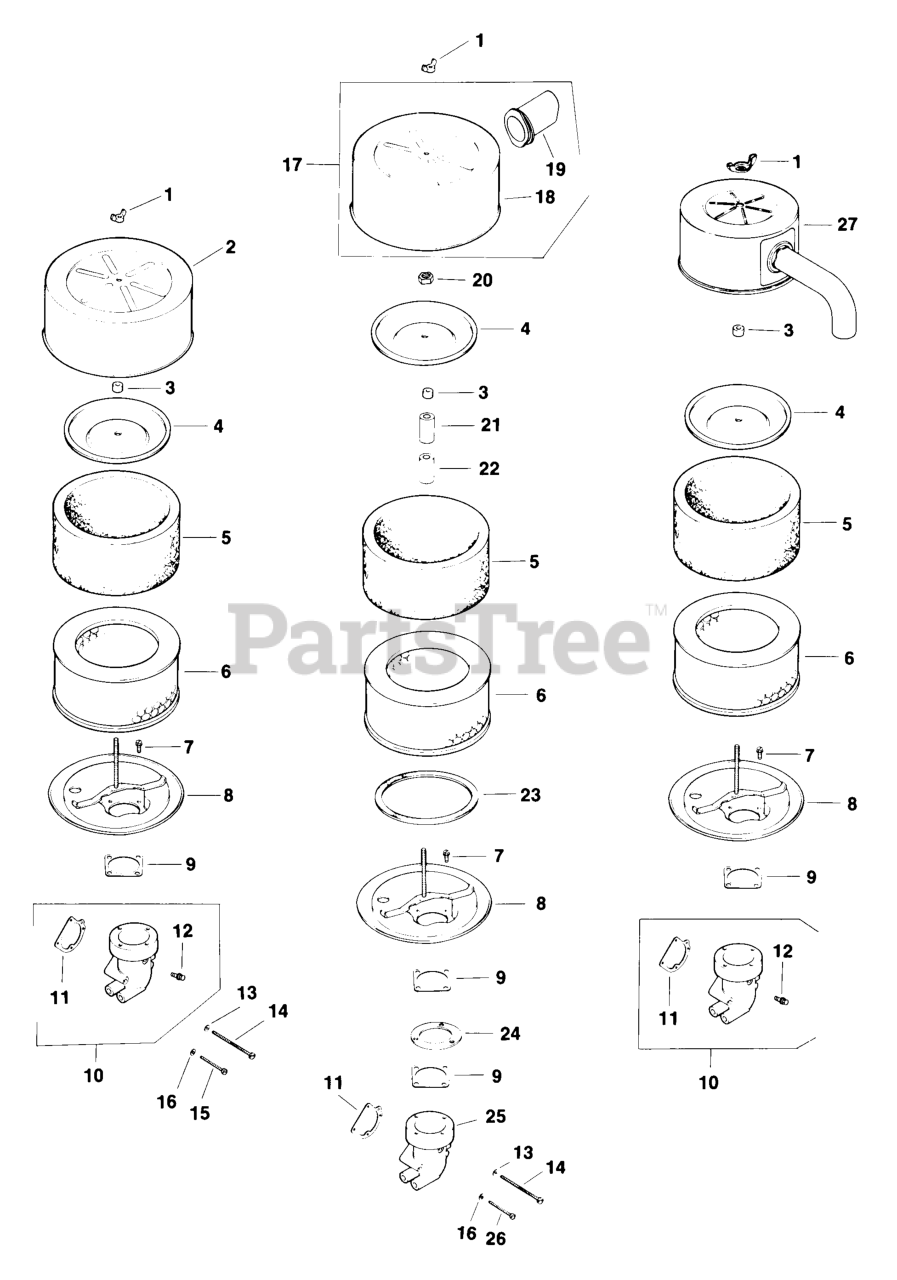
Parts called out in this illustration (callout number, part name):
1	NUT, WING 1/4-20 USE 25 100 15-S
3	SEAL, BREATHER
4	COVER, INNER AIR CLEANER
5	ELEMENT, PRE-CLEANER
7	SCREW, WSH HD TAP #10-32x9/16" USE 25 086 110-S
8	BASE - DISCONTINUED
9	GASKET, AIR CLEANER
10	KIT, ELBOW - (#DSC)
11	GASKET, AIR CLEANER ELBOW
12	SCREW, WSH HD TAP 1/4-20-5/8" - DISCONTINUED
13	WASHER, FLAT 3/16"
14	SCREW, SLT PAN HD 10-32X2 1/4"
15	SCREW, SLT PAN HD 10-32X1 1/2" USE 25 086 63-S
16	WASHER, INT TOOTH LOCK #10
